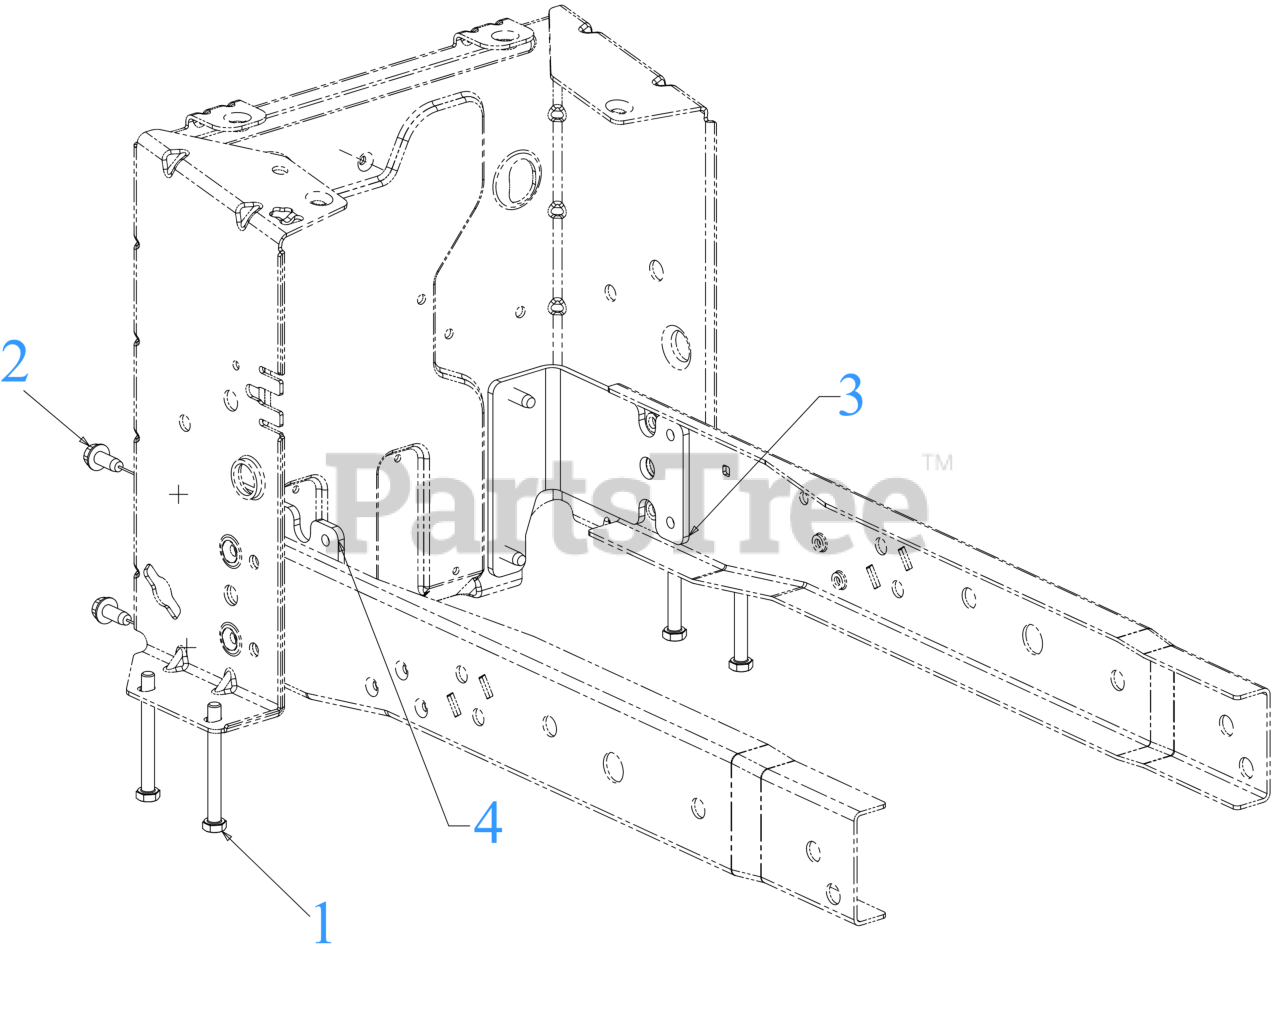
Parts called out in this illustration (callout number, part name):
1	HEX SCREW 5/16-18 x 3.00
2	SCREW 5/16-18 x .750
3	BRACKET SUPPORT SLEEVE (LH)
4	BRACKET SUPPORT SLEEVE (RH)
